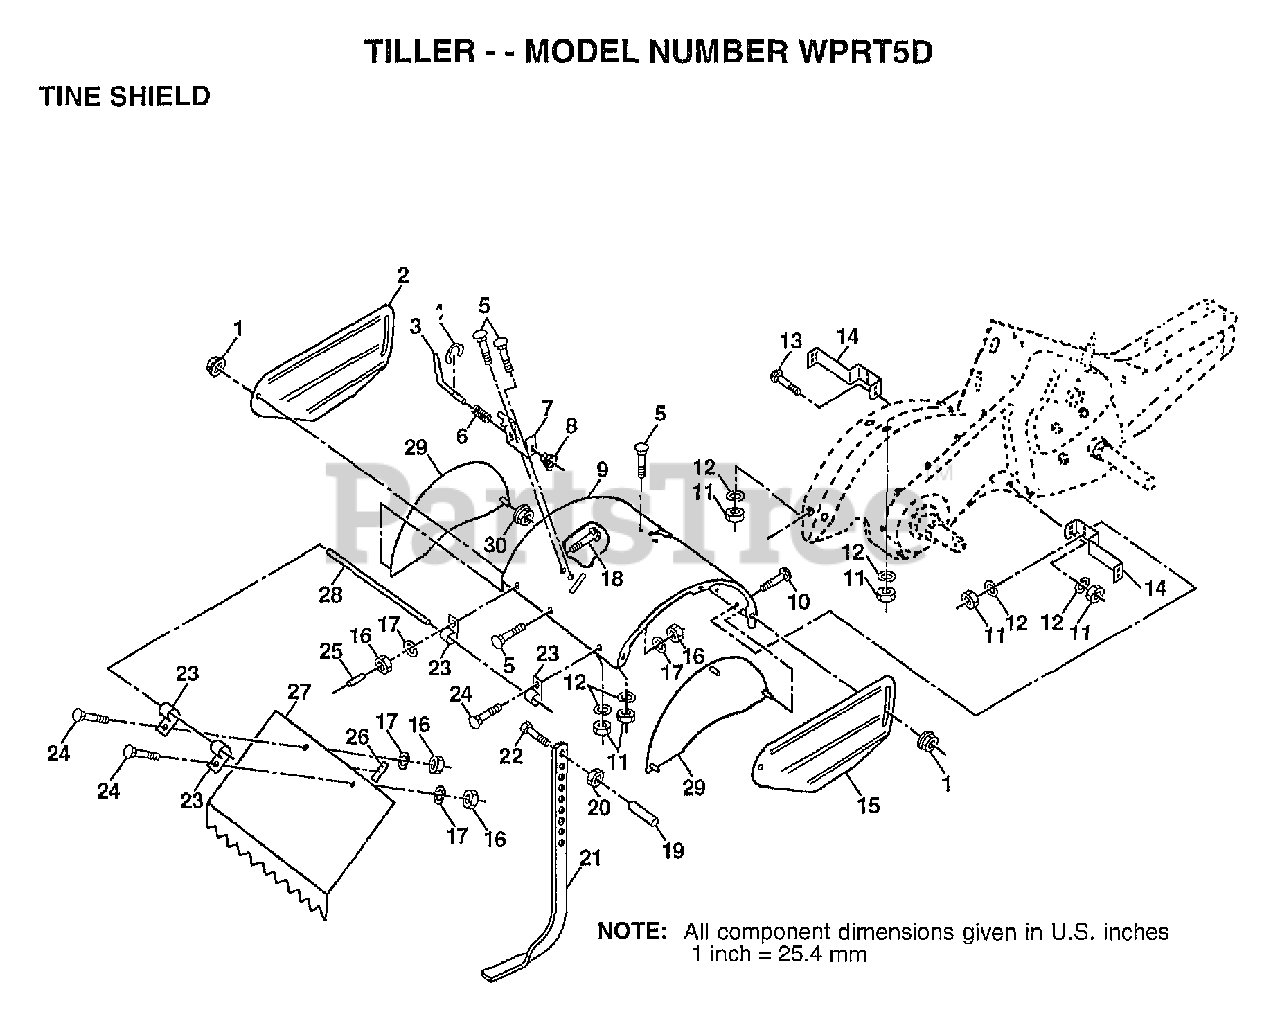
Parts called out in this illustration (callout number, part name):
1	NUT
2	SHIELD.SD.OUT.LH
3	STAKE PIN TI
4	KLIP RING TI
5	BOLT
6	SPRING TI
7	LATCH BRACKET TI
8	SPRING CRT
9	TINE SHIELD
10	BOLT
11	NUT.HEX.5/16-18
12	LOCKWASHER
13	BOLT
14	"BRACKET,SHIELD"
15	SHIELD.SD.OUT.RH
17	LOCKWASHER
18	BOLT
19	GRIP CRT
20	NUT.HEX.3/8-16UNC
21	STAKE DEPTH 16
22	BOLT
23	HINGE CRT
24	BOLT
25	VINYL CAP TI
26	PAD IDLER TI
27	LEVELING SHIELD
28	PIN HINGE
29	SIDE SHIELD
30	LOCKNUT TI
